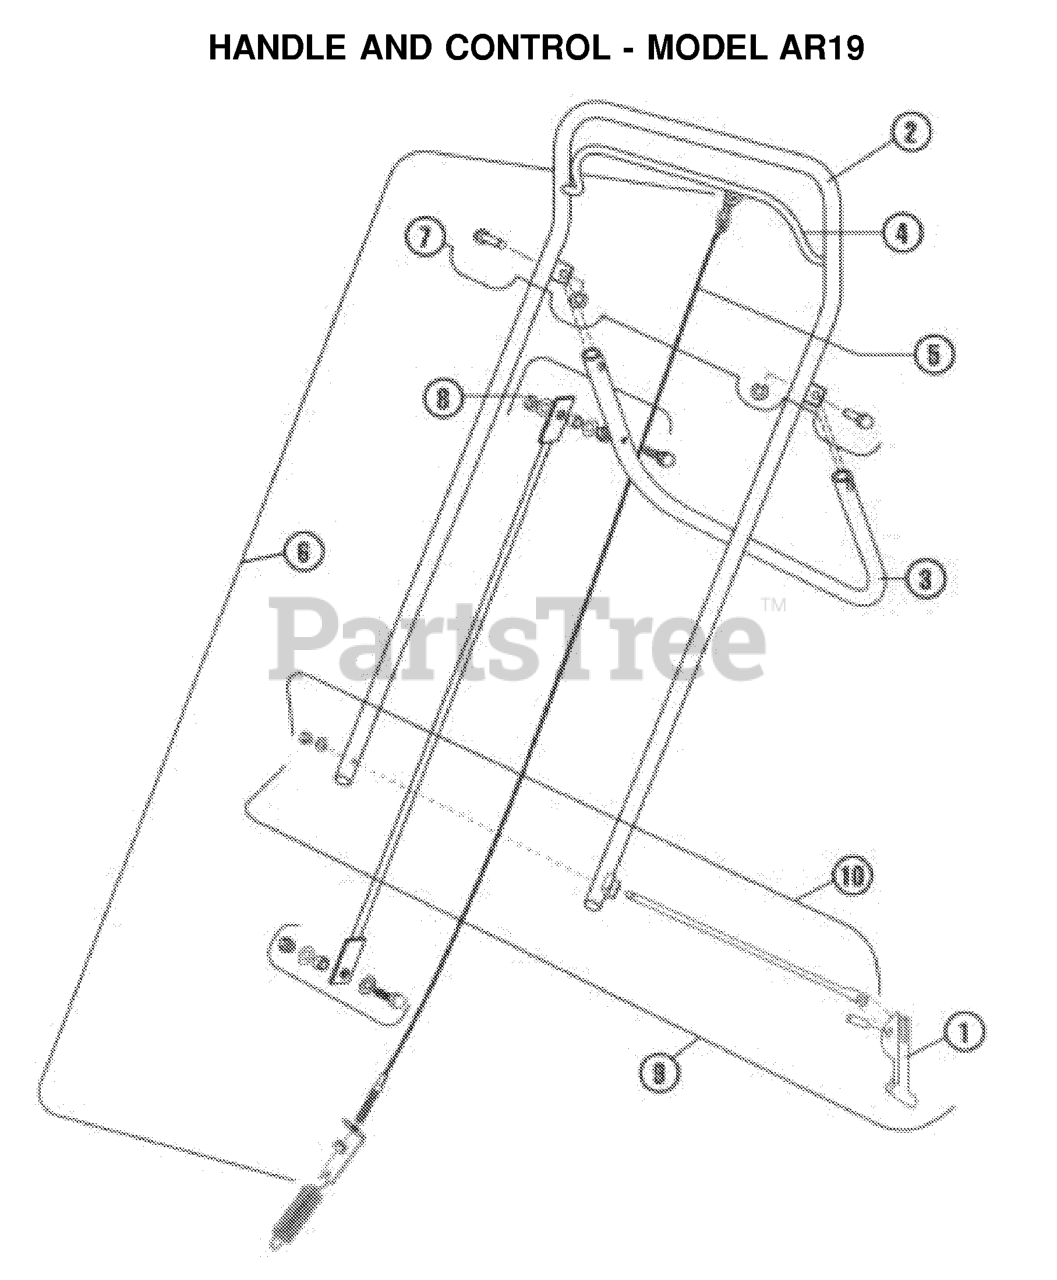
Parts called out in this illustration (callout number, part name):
1	CAM LOCKING LEVER
2	HANDLE
5	CLUTCH CABLE
6	CABLE KIT, CLUTCH
7	PIN KIT, REAR WHEEL
8	CONTROL ROD KIT HV
9	CAM ROD KIT W/O PIVOT SLIDE
10	CAM ROD KIT
